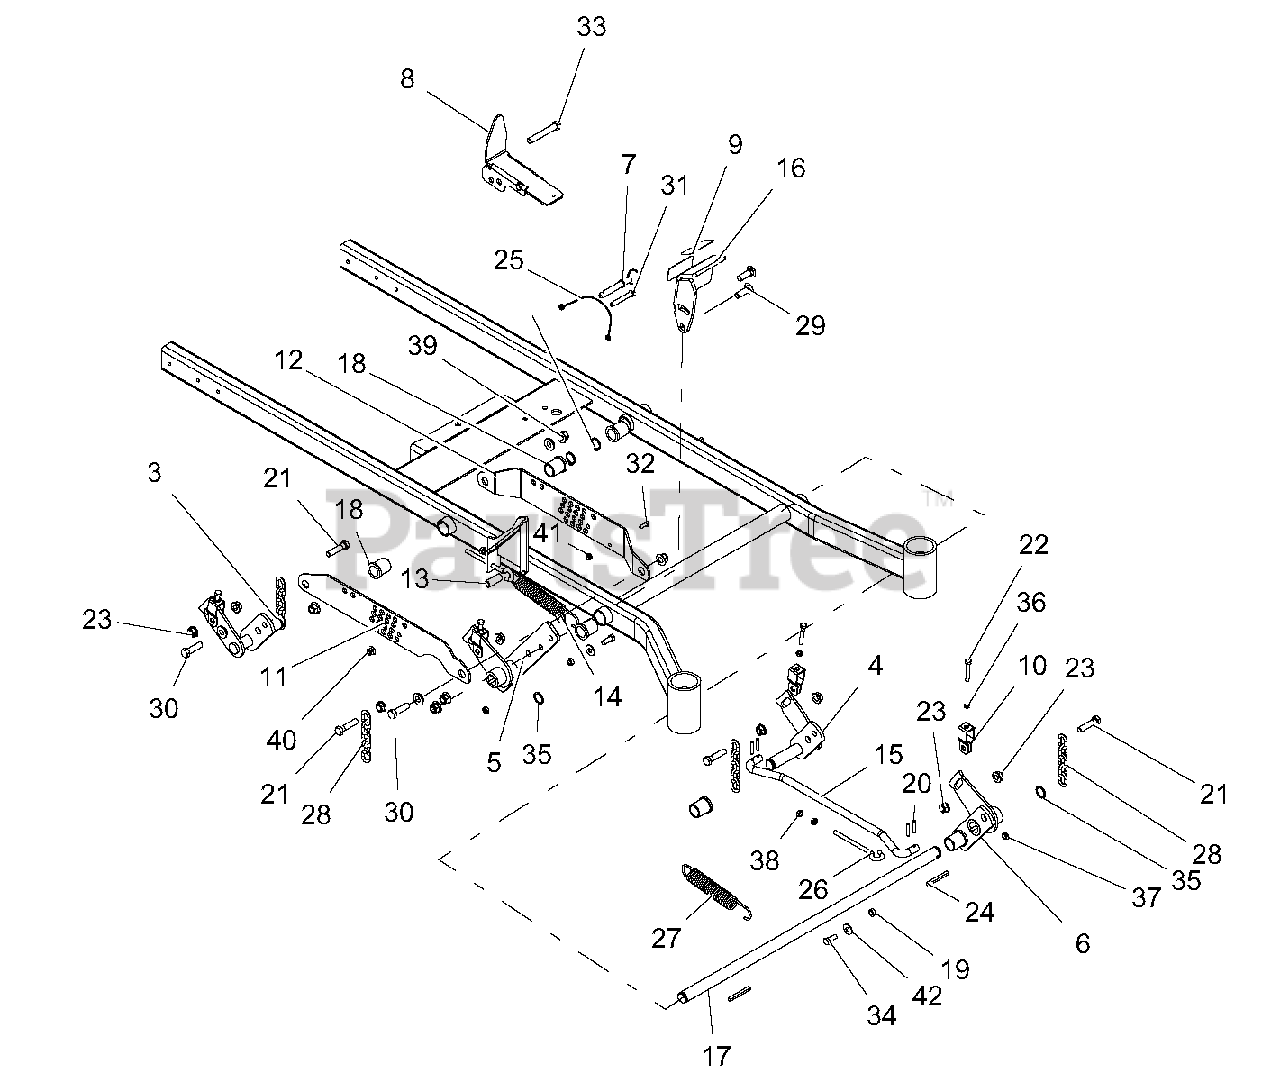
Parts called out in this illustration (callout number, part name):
3	WLDMT, REAR RH DECK LIFT
4	WLDMT, REAR LH DECK LIFT
5	WLDMT, FRONT RH DECK LIFT
6	WLDMT, FRONT LH DECK LIFT
7	PIN, .50 X 2.00 USABLE LG BALL
8	WLDMT, MECHANICAL LOCK-UP-BLACK
9	GRIP, PEDAL 1.50 X 3.00
10	BRKT, DECK LEVELING
11	BRKT, RH OUTBOARD LIFT/CUT HEIGHT-BLACK
12	BRKT, RH INBOARD LIFT/CUT HEIGHT-BLACK
13	SPACER, .375 X .625 X 1.54
14	BSHG-FLG .515X.750X.395X1.120
15	ROD, LIFT ASSIST 19.35"
16	PEDAL, ADJUSTABLE FOOT LIFT-BLACK
17	SHAFT, FRONT MOWER LIFT
18	BSHG-FLG 1.00X1.25X1.5X1.5
19	BSHG-SLV .377X.624X.235
20	PIN, ROLL .250 X 1.25 STAINLESS STL
21	BOLT, HEX M12-1.75 X 50 CLASS 8.8
22	BLT-HEX .312-18X2.00 FTH GR5YZ
23	NUT-SPNLK-FLG M12-1.75
24	KEY, SQ .25 X 2.50 X .25 SAE
25	LANYARD, 12"
26	BOLT, EYE .38-16X6.00 .62 DI A
27	SPRG, EXTENSION
28	CHAIN, MOWER LIFT
29	@BLT-RDHDSQNK .50-13X1.50 G5 YWZC
30	BLT-HEX .50-13X1.75 GR5 YWZC
31	BLT-HEX .38-16X2.50 GR5 YWZC
32	BLT-HEX .25-20X.75 GR5 YWZC
33	BLT-HEX .50-13X3.25 GR5 YWZC
34	BLT-HEX .38-16X1.00 GR5 YWZC
35	RG-RTNG-EXT 1.00X.078
36	NUT, JAM .312-18 YWZC
37	@NUT-LK-CTR-JAM .375-16 YWZC
38	NUT, JAM .375-16 YWZC
39	NUT-LK-NYL-FLG .50-13 YWZC
40	NUT-LK-NYL-FLG .38-16 YWZC
41	NUT-LK-NYL-FLG .25-20 YWZC
42	@WSHR-FL-STL.438X1.00X.083 YWZC
